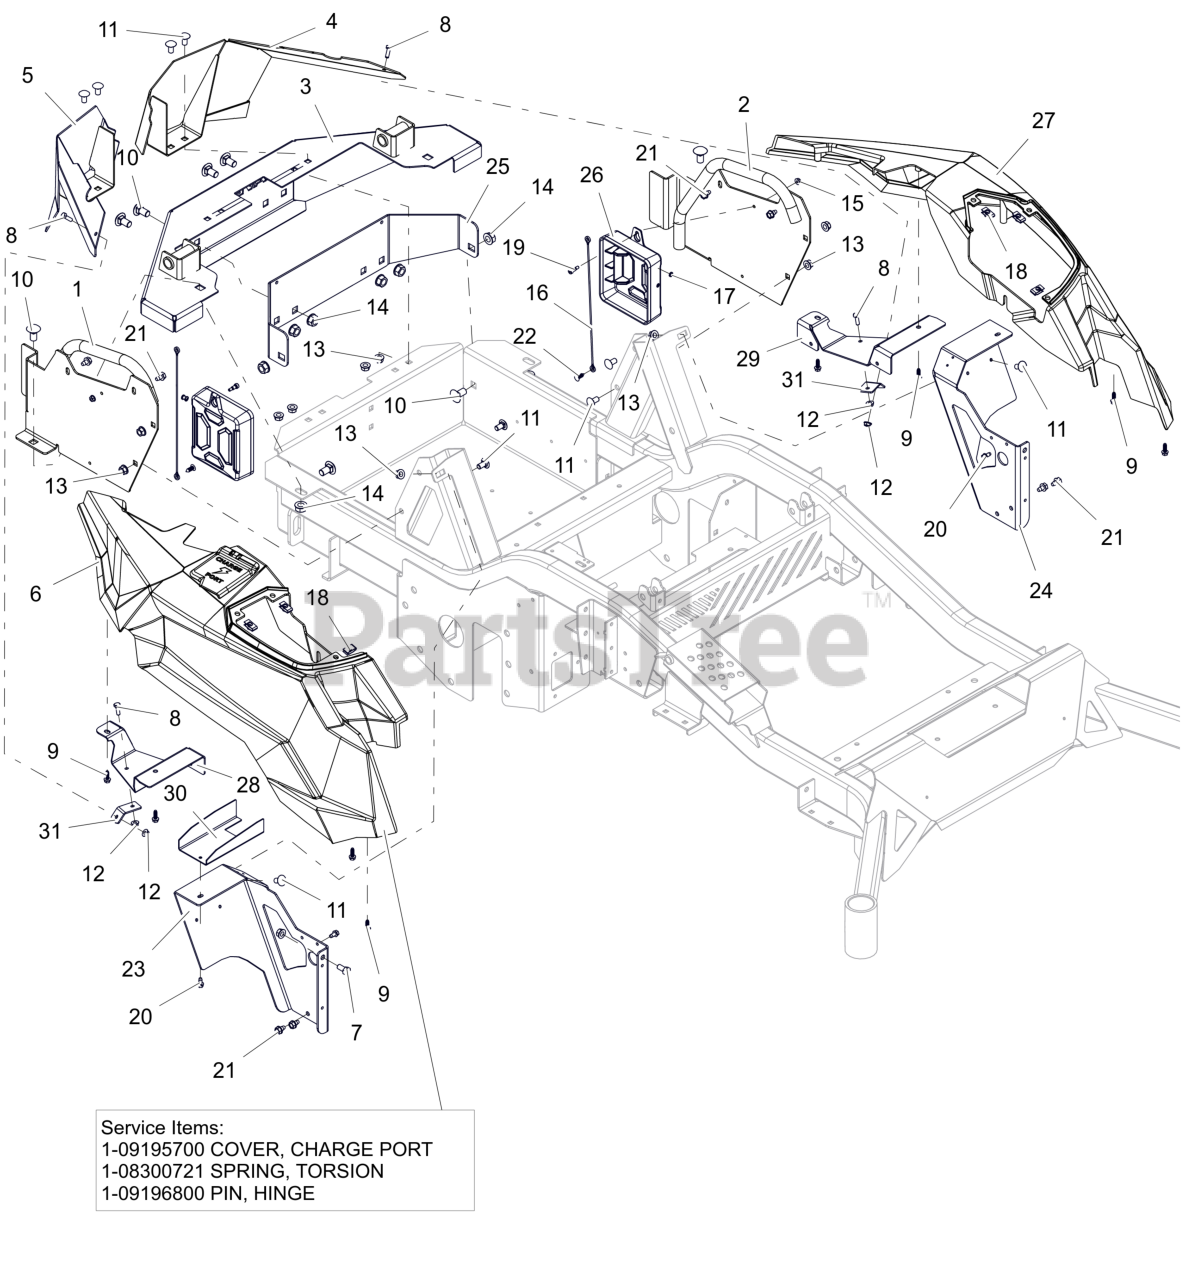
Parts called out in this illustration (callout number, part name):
1	WLDMT, REAR FENDER MOUNT-RH (RED)
2	WLDMT, REAR FENDER MOUNT-LH (RED)
3	WLDMT, BUMPER PT EV (RED)
4	WLDMT, REAR WRAP-LH (BLACK)
5	WLDMT, REAR WRAP-RH (BLACK)
6	ASM, FENDER RH PRO-TURN EV
6	COVER, CHARGE PORT
6	SPRING, TORSION
6	PIN, HINGE
7	BLT,HEX .38-16X.75 G5 ZCC
8	BLT, HEX .25-20X.75 G5 ZCC
9	SCR, PLASTITE-HWH 0.25 X 0.75 ZC120
10	BLT, RHSN .50-13X1.00 G5 ZCC
11	BTL,RHSSN .375-16 X 0.75 G5 FPB
12	NUT-LK-CTR-FLG .25-20 ZC120
13	NUT-LK-CTR-FLG .375-16 GF ZCC
14	NUT-LK-CTR-FLG .500-13 GG ZCC
15	NUT, FLG-TOP LK #10-24 GRF ZCC
16	CABLE, 12.0 LANYARD, NYLON
17	POST, & SCREW, PUSH LOCK .25 X .25
18	NUT-RTNR .25-20X.56
19	BLT-SHLDR .25X.375
20	SCR-TAP .25-20X.50 HWH ZCC
21	SCR,TAP .312-18X.50 HWH TR ZCC
22	RIVET, .25 NYLON PANEL
23	MOUNT, FRONT FENDER-RH
24	MOUNT, FRONT FENDER-LH
25	SUPPORT, BUMPER (BLACK)
26	COVER, BATTERY BUSBAR TERMINAL
27	FENDER, LH PRO-TURN EV
28	SHIELD, FENDER MOUNT -RH (BLACK)
29	SHIELD, FENDER MOUNT-LH (BLACK)
30	SHIELD, DEBRIS -CHARGE PORT (BLACK)
31	STRAP, SUPPORT - REAR WRAP (BLACK)
